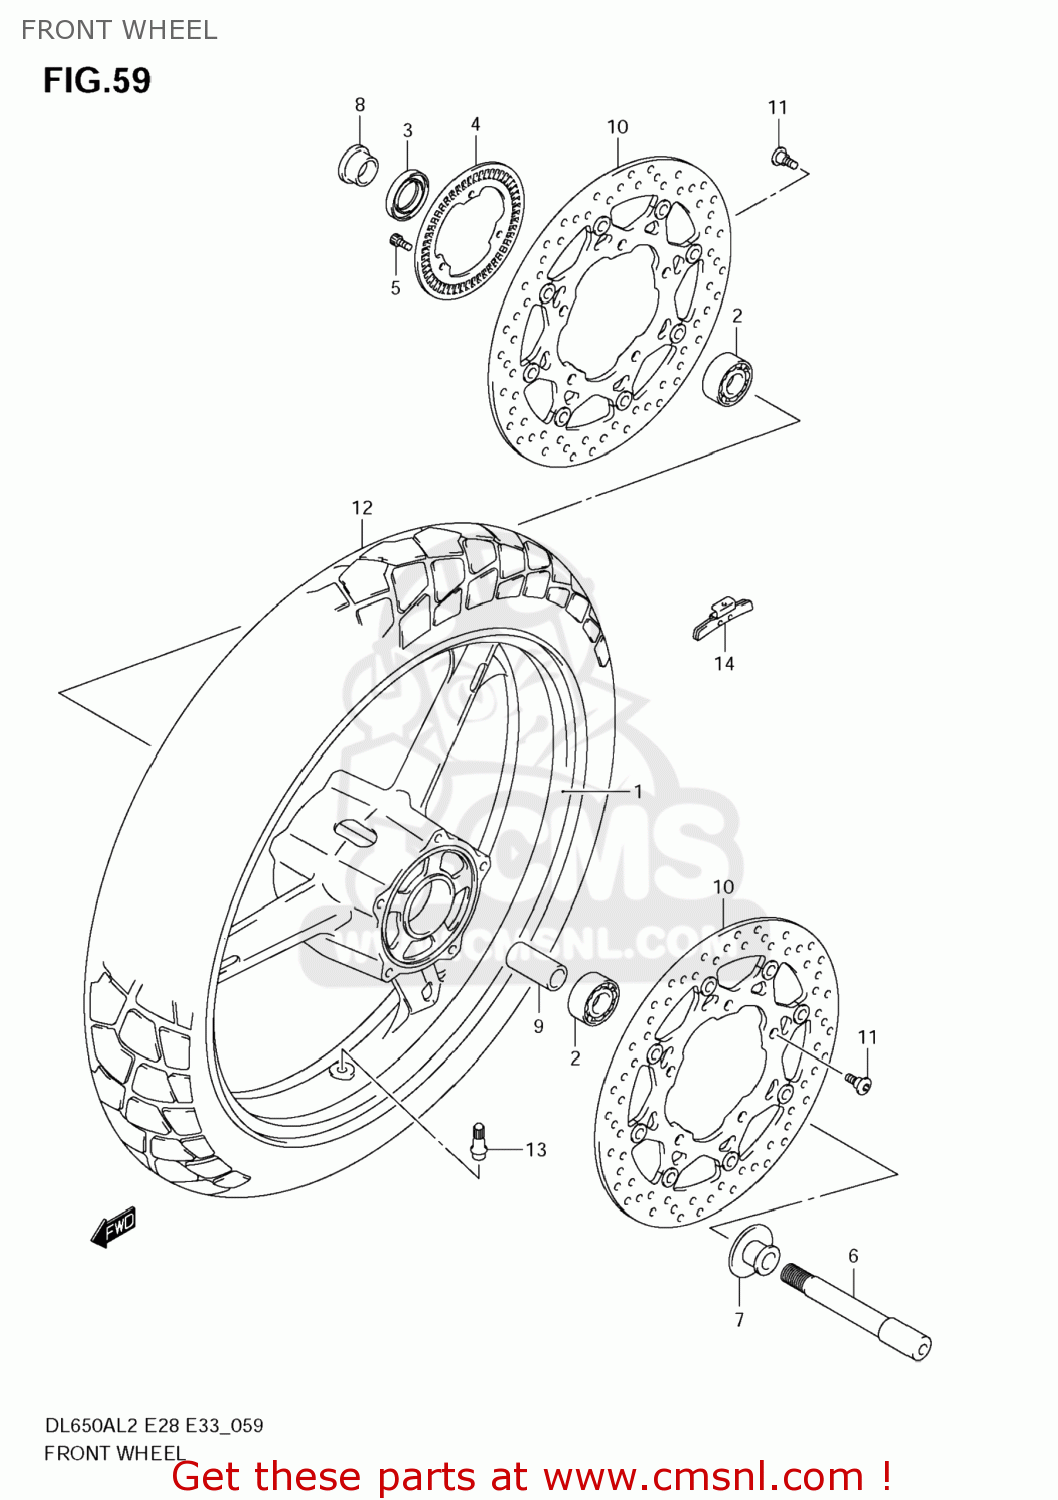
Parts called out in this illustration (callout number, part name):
1	WHEEL,FR(19M/CXMT2.50)
2	BEARING
3	SEAL,OIL(24X40X7)
4	RING,SPEED SENSOR FR(50T)
5	BOLT
6	AXLE,FR
7	SPACER,FR AXLE,L
8	SPACER,FR AXLE
9	SPACER(17.5X25X88)
10	DISC,FR BRAKE
11	BOLT(8X21)
12	TIRE,FRONT,110
13	VALVE ASSY,WHEEL RIM(TR412)
14	WEIGHT,WHEEL BALANCE 10G
